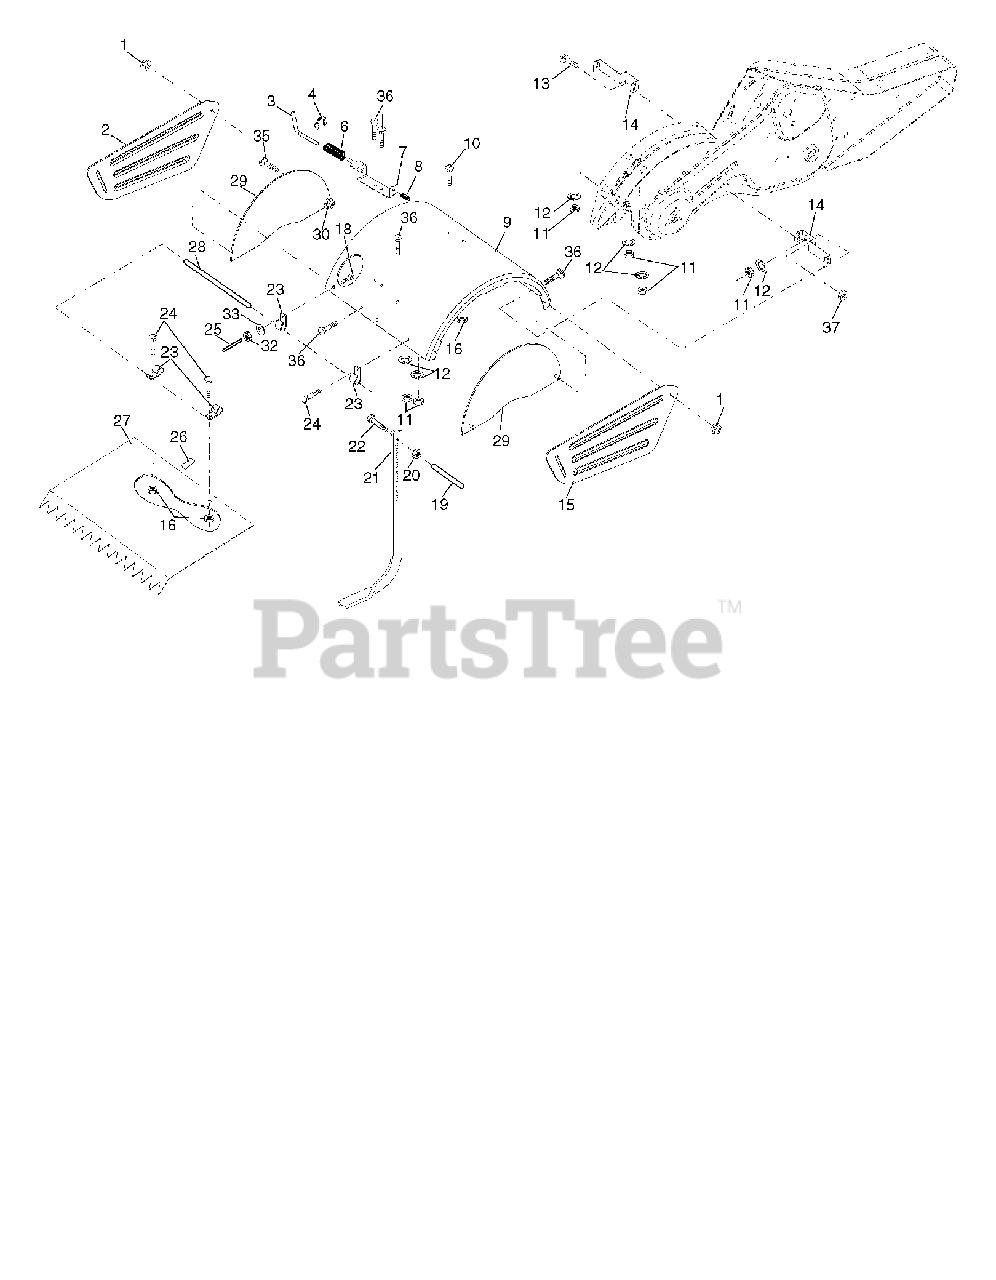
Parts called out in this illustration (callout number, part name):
3	STAKE PIN TI
4	RING, KLIP
5	BOLT, RDHD SQNK 5/16-18 X 3/4
6	SPRING TI
7	LATCH BRACKET TI
8	SPRING CRT
10	BOLT, RDHD SQNK 5/16-18 X 3/4
12	LOCKWASHER
13	BOLT.CARRIAGE.5/16-18
14	BRACKET.TINE.SHIELD.TILLER.BLA
16	NUT T
19	GRIP CRT
20	NUT.HEX.3/8-16UNC
21	STAKE.DEPTH.16.CRT.BLACK
22	BOLT.375-16
23	HINGE CRT
26	PAD IDLER TI
27	SHIELD.TILLER.LEVELING.YELLOW
28	PIN.HINGE.TILLER
29	SHIELD.SIDE.OUTER.RH.YELLOW
30	LOCKNUT-FLANGE 5/16-18
32	NUT
33	LOCKWASHER
